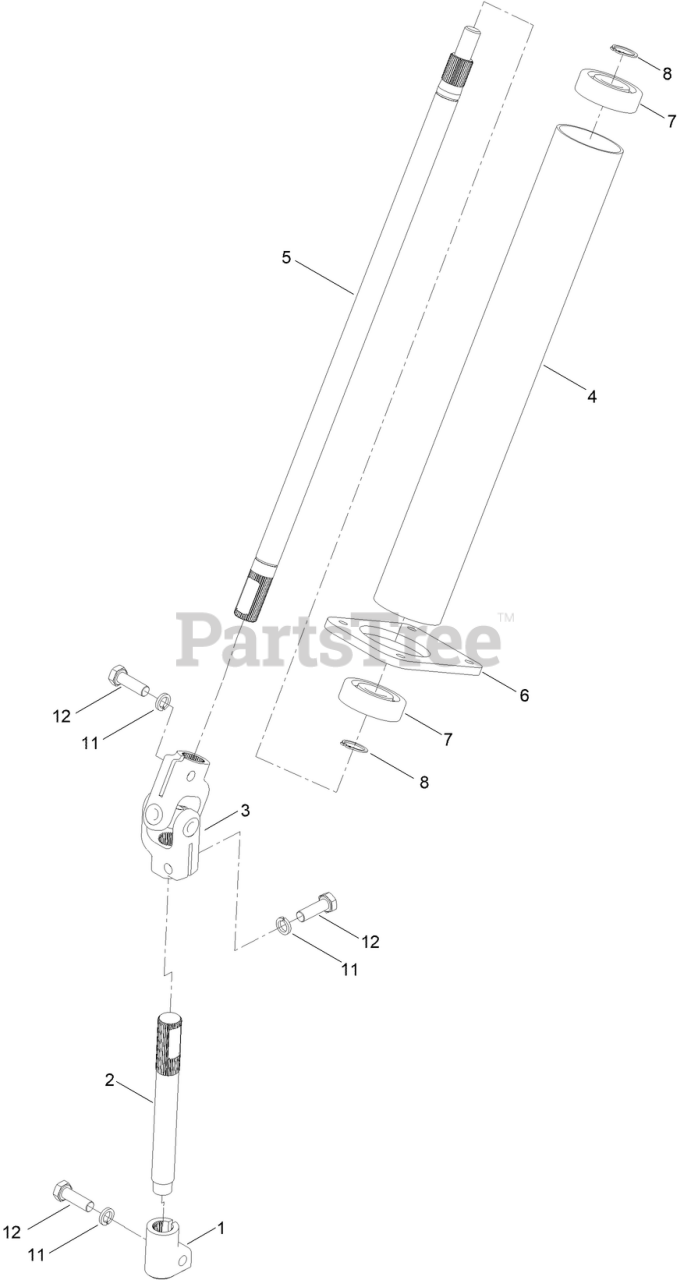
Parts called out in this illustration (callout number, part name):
1	CONNECTION, STEERING RACK
2	LOWER ROD, STEERING RACK
3	UNIVERSAL JOINT
4	COVER, UPPER STEERING ROD
5	UPPER ROD, STEERING
6	PLATE, MOUNTING STEERING ROD
7	BEARING, STEERING
8	CLIP, STEERING BEARING
11	WASHER, LOCK
12	BOLT, STEERING
